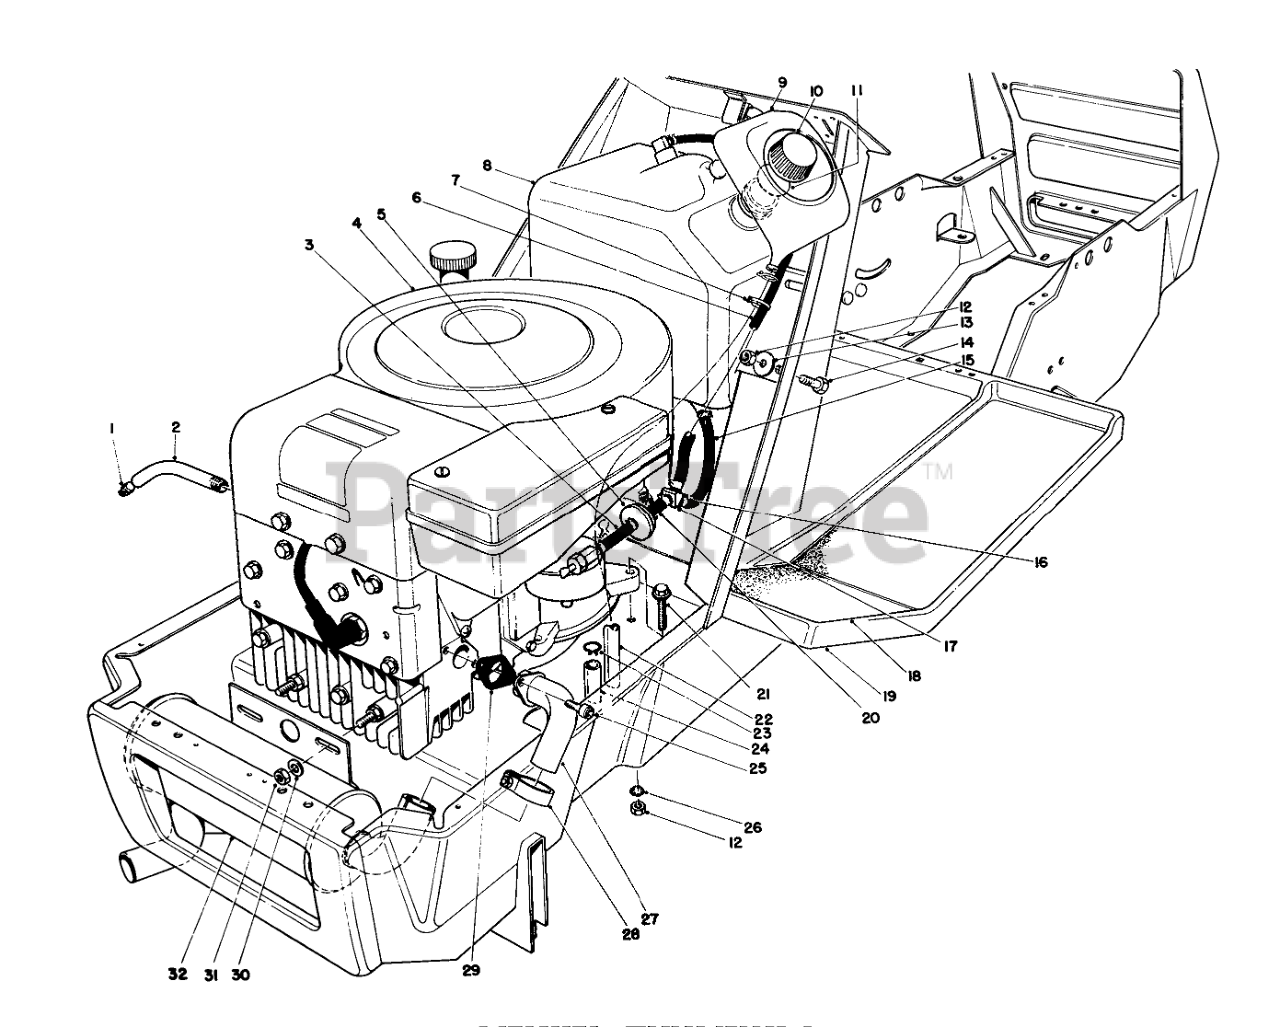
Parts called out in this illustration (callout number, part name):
1	PLUG-PIPE, SQH
2	OIL DRAIN TUBE
3	Hose-Gas
4	Engine
5	Fuel Filter
6	HOSE -RETURN
7	TIE-CABLE
8	Gas Tank Assy. (Incl. Ref. #9)
9	Funnel-Overflow
10	Gas Cap Assy. (Incl. Ref. #11)
11	GAS CAP GASKET
12	NUT-LOCK, NI
13	WASHER
14	SCREW-HH
15	HOSE-FUEL
16	FUEL HOSE CLAMP
17	Fitting-Barbed Y
18	LH FOOT TREAD
19	Frame
20	GAS HOSE
21	SCREW-HH
22	Hose Funnel
23	HOSE CLAMP
24	CARB DRAIN HOSE
25	SCREW-HSH
26	WASHER-LOCK, INTERNAL
27	10 HP EXHAUST PIPE WA
28	MUFFLER CLAMP
29	Exhaust Gasket
30	WASHER-PLAIN
31	NUT-LOCK, CONE
32	EXHAUST MUFFLER 10 HP
